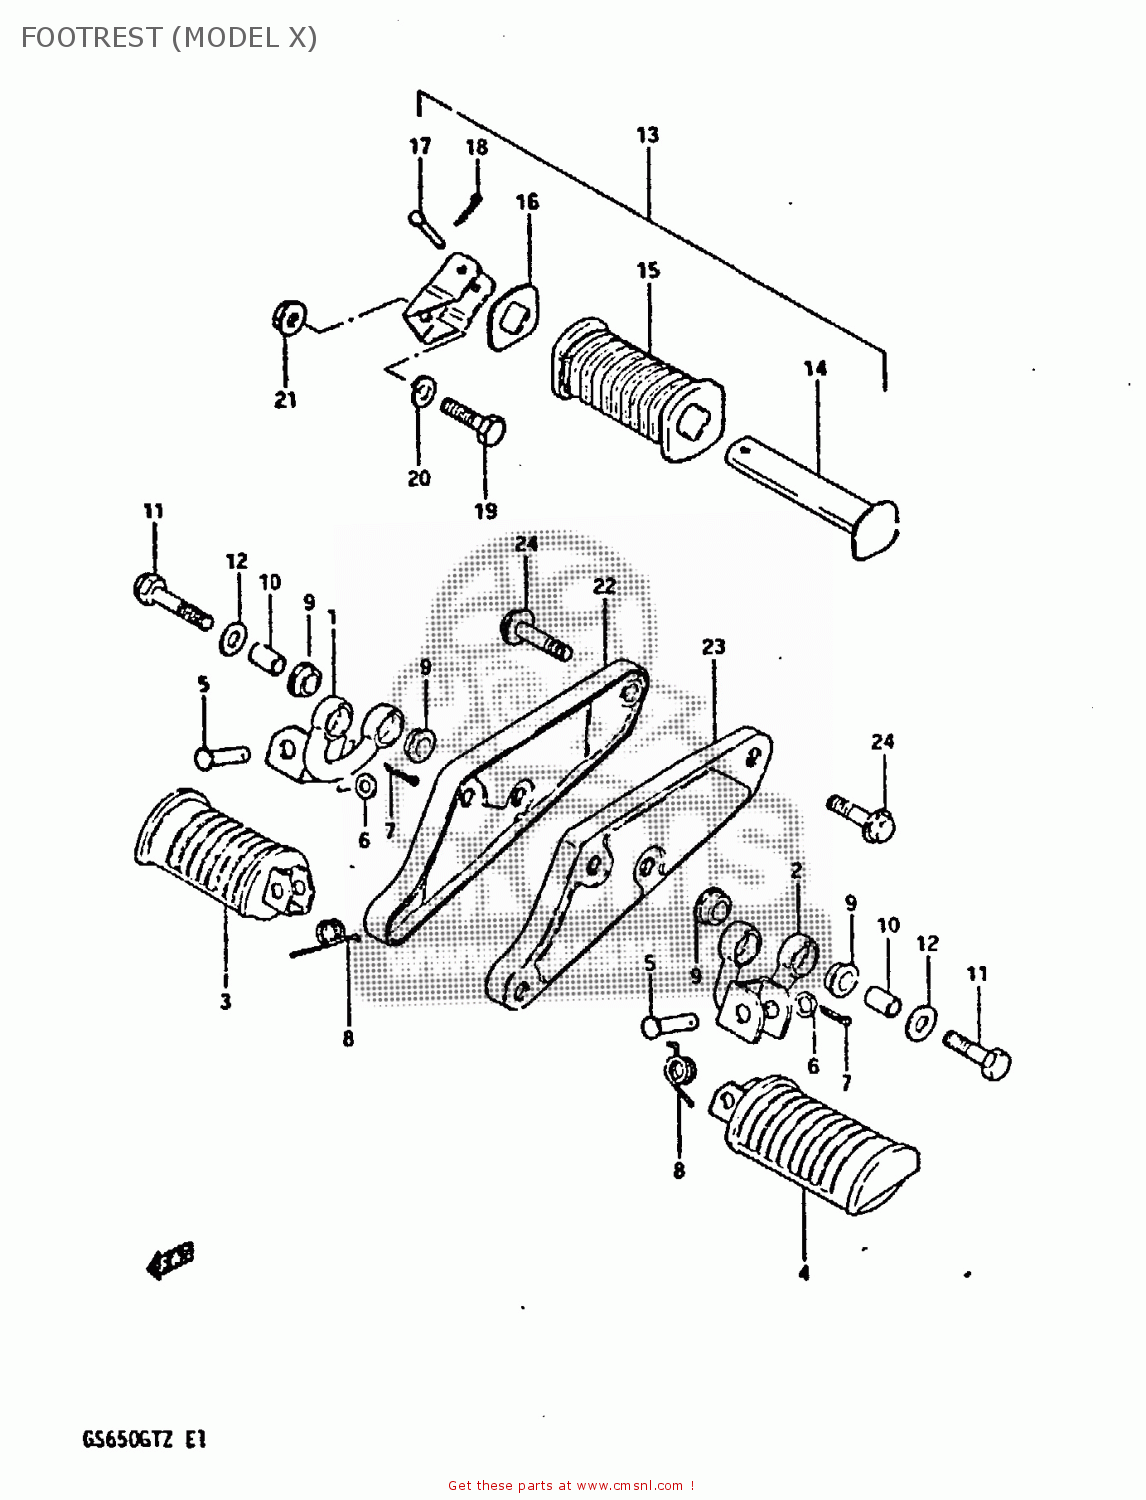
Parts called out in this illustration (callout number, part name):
1	BAR,FRONT FOOTREST
2	BAR,FRONT FOOTREST,LEFT
3	RUBBER,PILLION FOOTREST,R
4	RUBBER,PILLION FOOTREST,L
5	PIN
6	WASHER
7	PIN
8	SPRING
9	BUSH
10	SPACER (10.2X14X20)
11	BOLT
12	WASHER(10.5X28X2.3)
13	FOOTREST ASSY,PILLION,R
14	BAR,REAR FOOTREST,LEFT
15	RUBBER,PILLION FOOTREST
16	WASHER,FOOTREST RUBBER
17	PIN
18	PIN
19	BOLT,M10X1.25X
20	LOCK WASHER
21	NUT
22	BRACKET
23	BRACKET
24	BOLT
